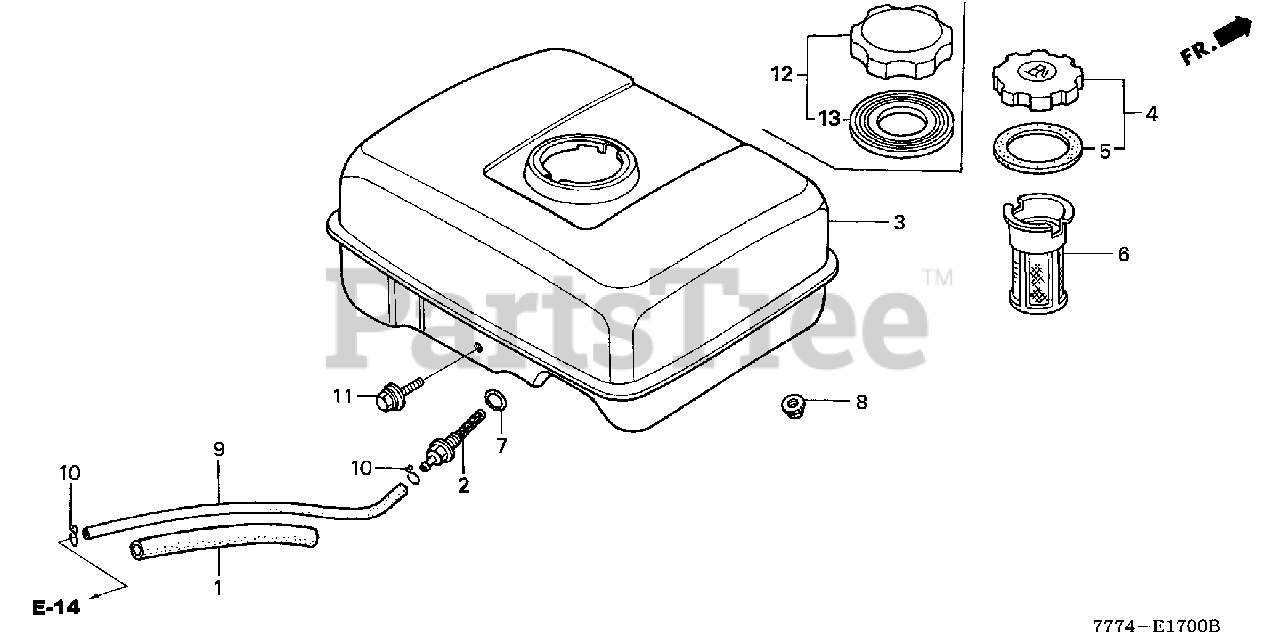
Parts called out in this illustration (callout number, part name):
1	RUBBER, SUPPORTER (107MM)
2	JOINT, FUEL TANK
3	TANK, FUEL *R280* (POWER RED)
6	FILTER, FUEL (N/A: USE FILTER 17672-887-791 + FILTER HOLDER 17673-893-000)
7	O-RING (14MM) (ARAI)
8	NUT, FLANGE (6MM)
9	BULK HOSE, FUEL (4.5X3000) (4.5X140)
10	CLIP, TUBE (B8)
11	BOLT, FLANGE (6X34)
12	CAP, FUEL FILLER (CHROME PLATED)
13	GASKET, FUEL FILLER CAP (39X62X3)
